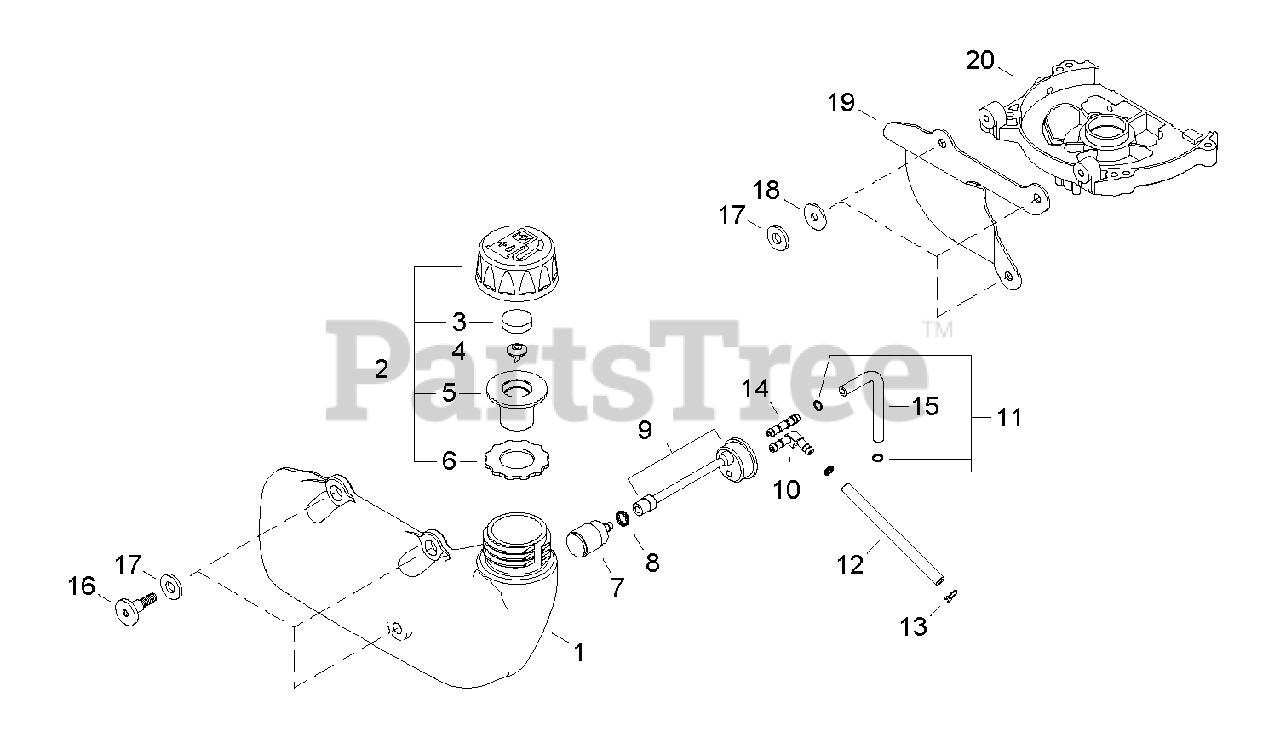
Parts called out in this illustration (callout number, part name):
1	TANK, FUEL
2	CAP ASSY
4	VENT, FUEL TANK
5	HOLDER, VENT
6	GASKET, CAP
7	FILTER, FUEL
8	CLIP - 7.8
9	FUEL PIPE ASSY
10	CONNECTOR, PIPE
11	CLIP - 6
12	PIPE - RETURN
13	CLIP - BUTTERFLY
14	CONNECTOR, PIPE
15	PIPE - FUEL
16	BOLT - 5
17	WASHER - 6
18	WASHER - 5
19	SHIELD, HEAT
20	CRANKCASE ASSY - FRONT
